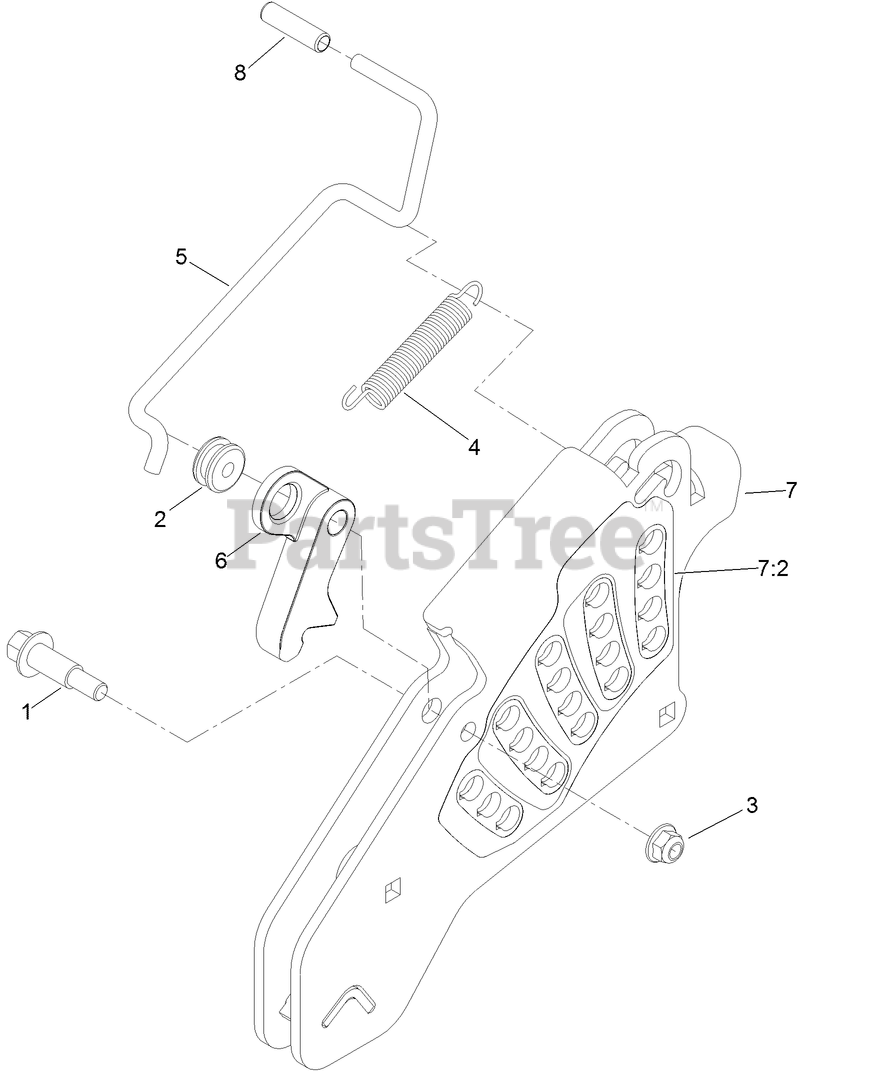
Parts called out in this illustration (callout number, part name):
1	BOLT-SHOULDER
2	GROMMET
3	NUT-HF, NI
4	SPRING-EXTENSION
5	ROD-LOCK, TRANSPORT
6	PAWL-TRANSPORT, HOC
7	PLATE-HEIGHT ADJUSTER
7:2	DECAL-HOC
8	GRIP-LEVER
